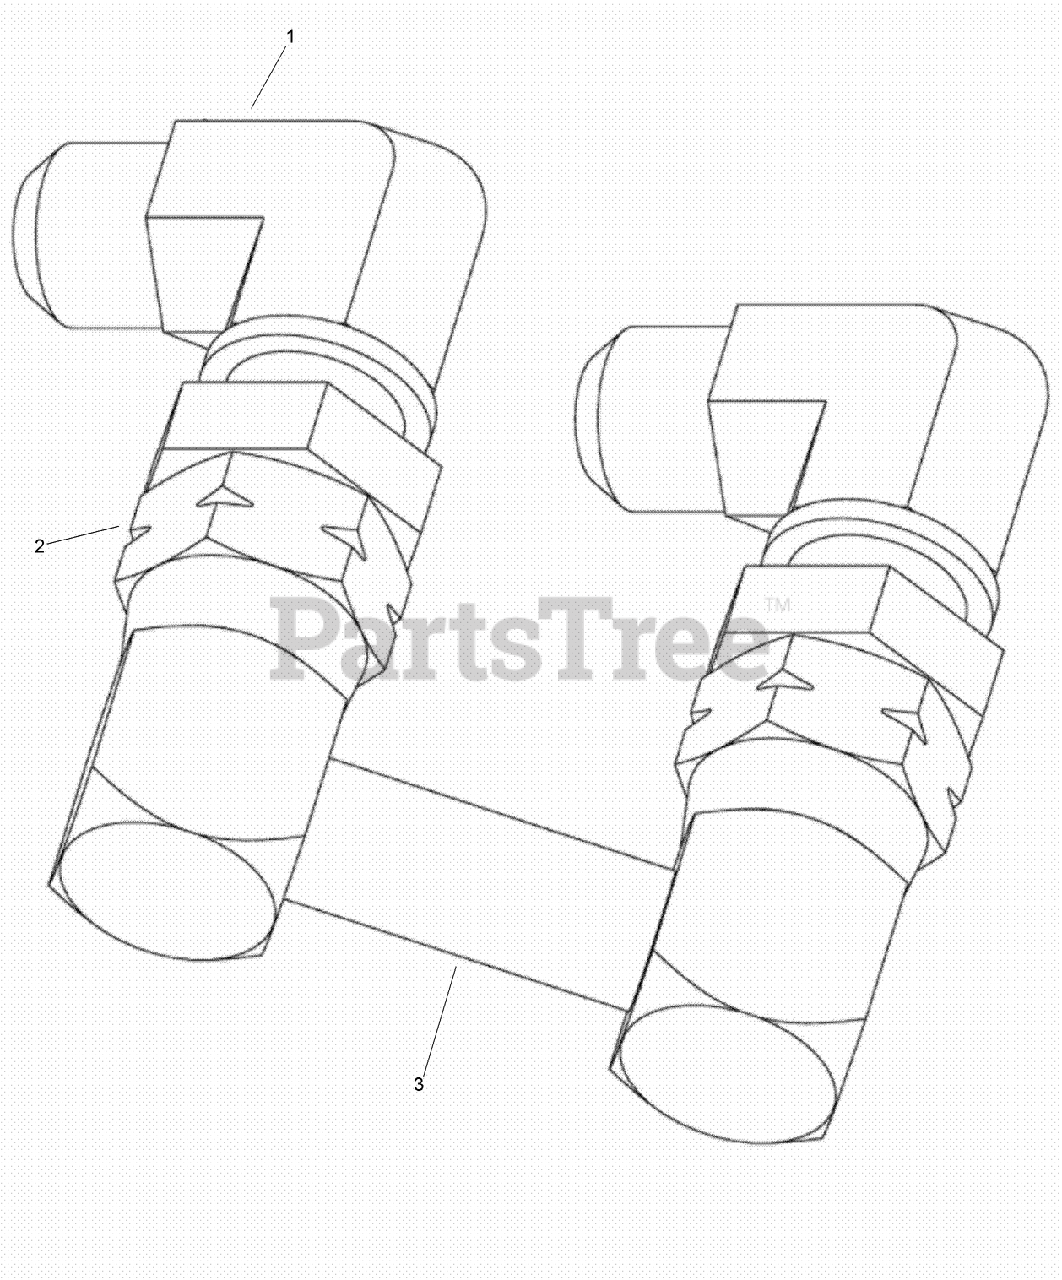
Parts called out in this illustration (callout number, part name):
1	FITTING-ELBOW, 90
2	NUT-LOCK, BULKHEAD
3	FITTING-SPECIAL
